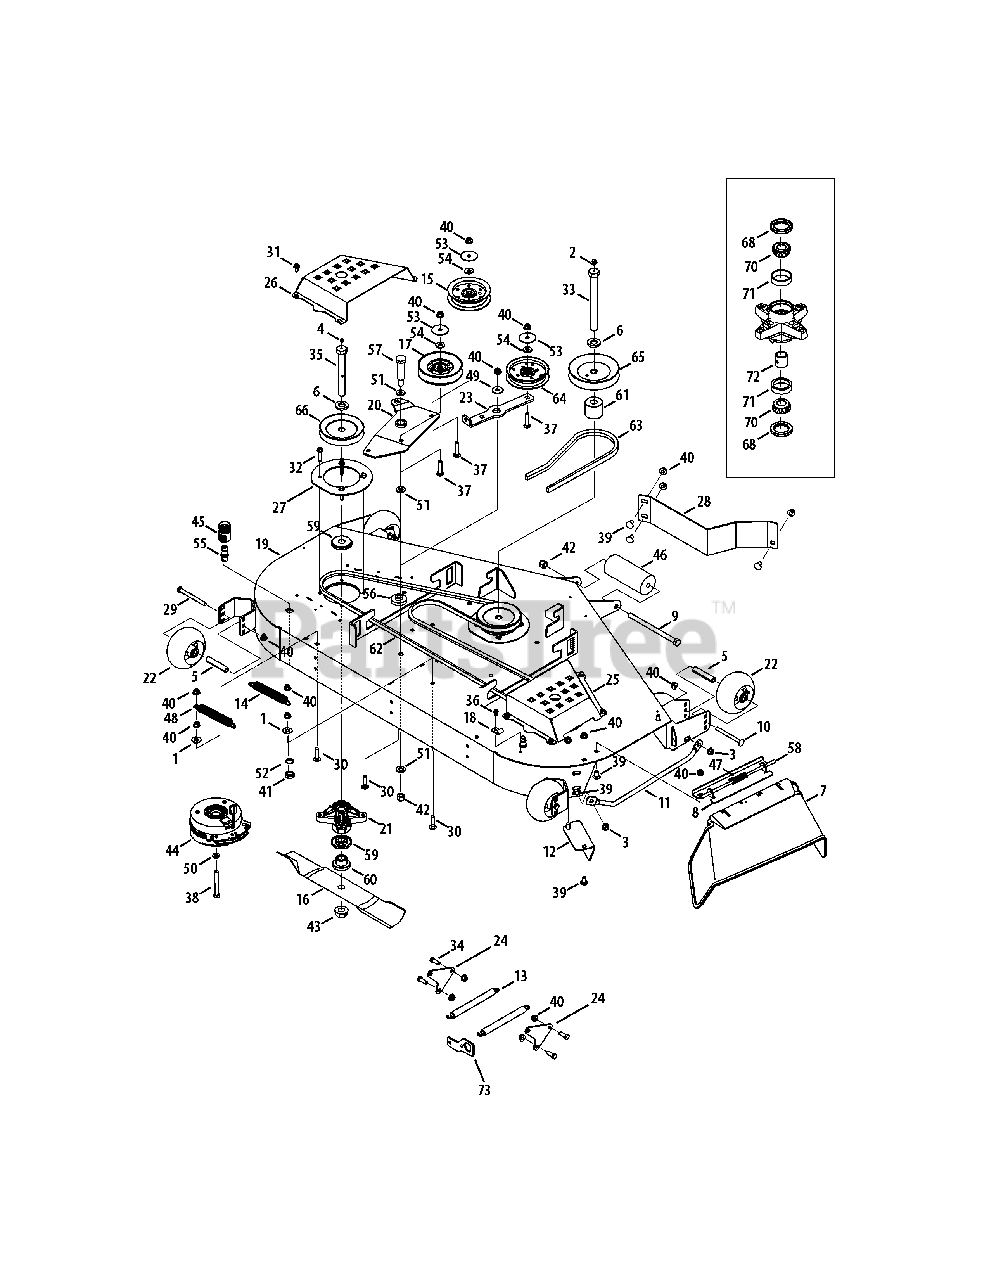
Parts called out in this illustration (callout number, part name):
1	Washer, .532x1.06x.094, Sae, Z
2	Fitting, St, Gres, 90, 1/4-28x.788
3	Nut, Flg, Ctrlck, 3/8-16, Gr-5, Yz
4	Fitting, Gres, Strgt, 1/4-28
5	Spacer, St, .390x.620x3.04, Yz
6	Spacer, .812x1.47x.218, Gr8, Yz
7	Chute, Dfl, Deck, Fab
8	Bracket, Chute, Dfl
9	Screw, 1/2-20, 7.50 Gr5, Pl
10	Bolt, Crg, 3/8-16x4.00, Gr5, Yz
11	Guard, Finger, Chute, Deck, Fab
12	Baffle, Chute, Micro
13	Spring, Extn, Hook, .75x7.89x.14, Bz
14	Spring, Extn, Hook, .94x7.57x.14, Z
15	Pulley, Idler, 4.88 Od
16	Blade, 19.0, Hi-Lift, 0.756id
17	Pulley, Idler, 5.06 Dia, Riveted
18	Bracket, Hook, Retainer
21	Spindle Asm, Deck
22	Wheel, Compl, 5.00 Dia
23	Arm, Idler, Deck
29	Screw, 3/8-16, 4.00, Gr5, Std
30	Carriage Bolt - 3/8x16x1.50lg
31	Screw, Tt, 5/16-18, .750, Hxindwsh
32	Screw, Tt, 5/16-18, 1.50, Hxindwsh
33	Screw, 3/4-16 X 7.7, Gr5, Spec
34	Screw, 3/8-16, 1.00, Gr5, Std
35	Screw, 3/4-16, 6.00, Gr5, Spec
36	Screw, Tt, 1/4-20, 0.500, Hxindwsh
37	Screw, Crg, 3/8-16, 1.75, Gr5
38	Screw, 7/16-20, 3.25, Gr5, Lock
39	Bolt, Crg, 3/8-16, 0.75, Shrt Nk
40	Nut, Flglk, 3/8-16, Grf, Nylon
41	Nut, Hex, M16-1.5 Din 936
42	Nut, Hexlk, 1/2-20, Gr2, Nylon
43	Nut, Flglk, 3/4-16, Gr8
44	Clutch, Elec, Brake 125 Ft-Lbs
45	Adap, Water Nozzle
46	Front Roller
47	Spring, Torsn, 180, .639x2.16x.12, Yz
48	Spring, Extn, .91 Dia X 7.33
49	Washer, Flat, .411 X 1.25 X .100
50	Washer, Lock, 7/16, SPlate, Reg
51	Washer, Flat, .510 X 1.000 X .125
52	Washer, Lock, Schnorr 17x23.8x1.95
53	Washer, Flat, .406 X 1.92 X .060
54	Washer, Flat, .406x1.000x.105
55	Nozzle, Deck, Water
56	Spacer, Shldr, .854 X .280
57	Bolt, Shldr .74 Dia X 2.4 Lg
58	Rod, Dfl, Chute
59	Spacer, Spindle, Deck
60	Spacer, Spindle, .76 X 2.0 X 1.1 Lg
61	Spacer, .760 X 2.000 X 1.69
62	Belt, Vtype, A Secx114.24aramid
63	Belt, B-Section, 91.04lg, Rzr
64	Pulley, Idler, 4.25"Dia
65	Pulley, V Typ, 5.768 Dia Split
66	Pulley, V Type A Sect X 4.90
68	Seal, Oil, Single Lip
70	Bearing, Cone, .750" Tapered Roller
71	Cup, Bearing, .750" Tapered Roller
72	Bearing Spacer
73	Spring Mount Bracket
